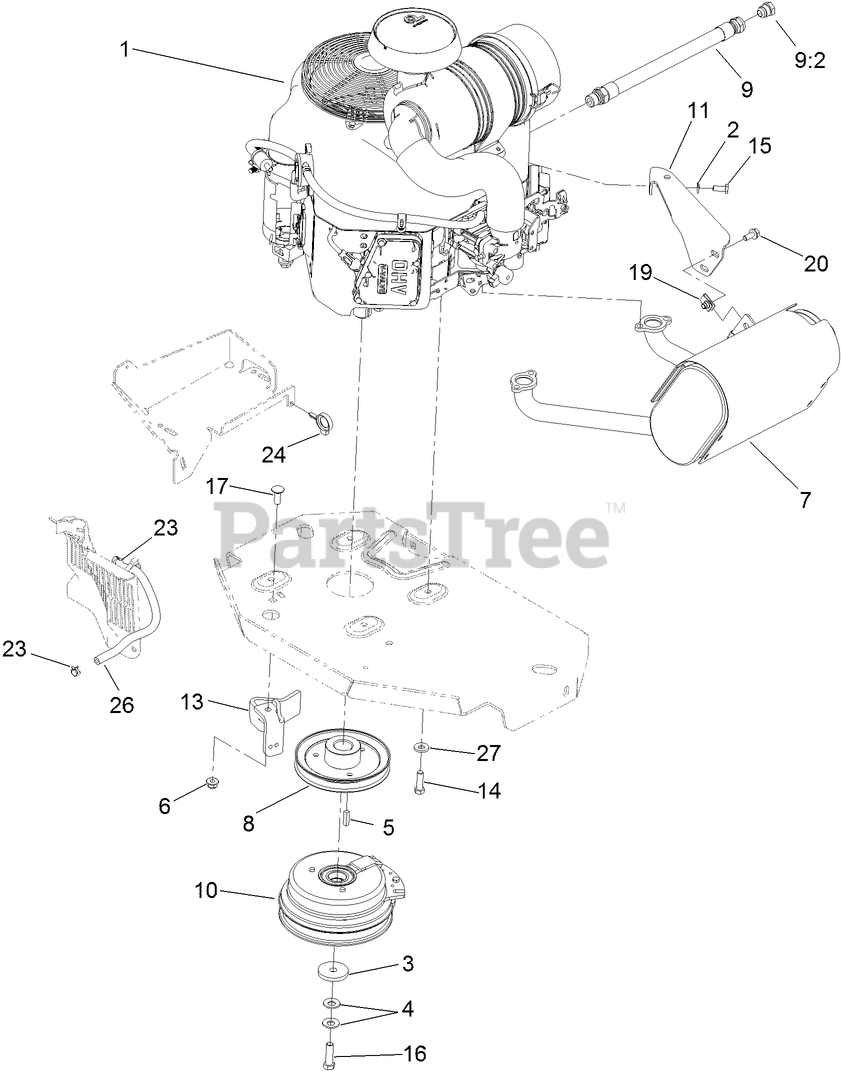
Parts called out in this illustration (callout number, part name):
2	WASHER-SPRING
3	WASHER-CLUTCH
4	WASHER-SPRING
6	NUT-HF, NI
7	MUFFLER
8	SHEAVE-PUMP, DRIVE
9	OIL DRAIN HOSE ASM
10	CLUTCH KIT
11	BRACKET-MUFFLER
13	CLUTCH-ANCHOR
14	SCREW-HH
15	SCREW-HH
16	SCREW-HH, W/LOCTITE
17	SCREW-CARR
19	NUT-U
20	SCREW-HHF
23	CLAMP-HOSE
24	CLAMP-HOSE
26	HOSE-FUEL
27	WASHER-BELLEVILLE
